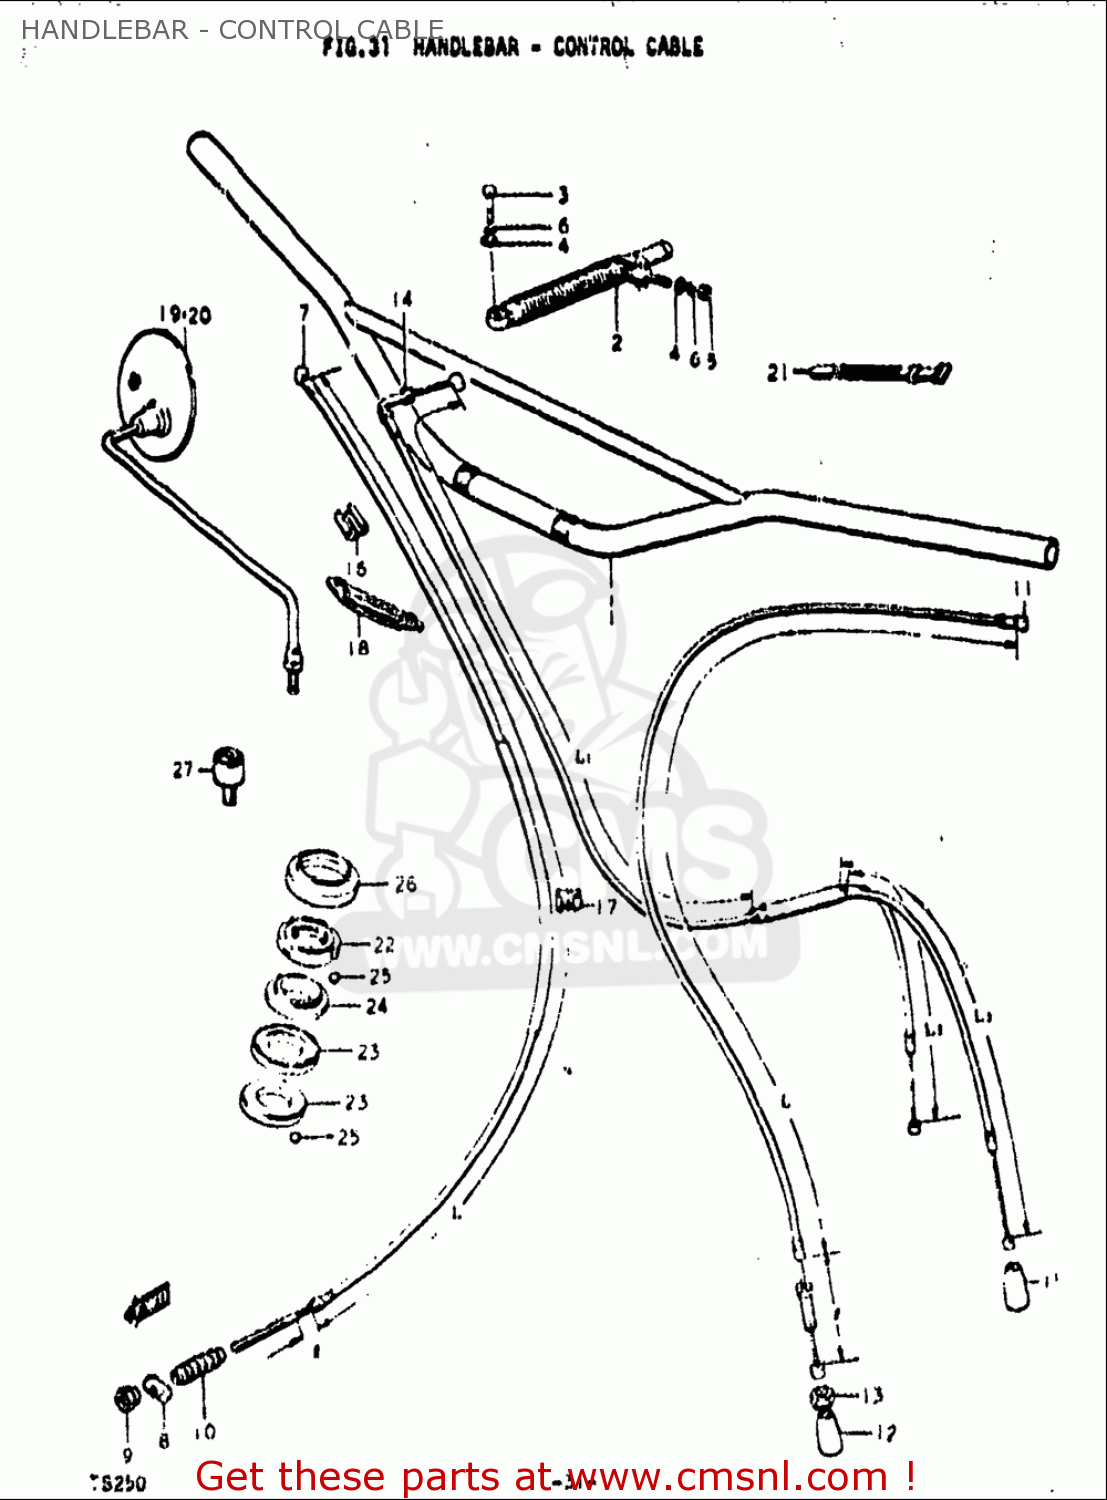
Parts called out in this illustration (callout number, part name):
3	BOLT
4	WASHER
5	NUT
6	WASHER,LOCK
7	CABLE,FR BRAKE
8	PIN(13X18)
9	NUT
10	SEAL,DUST
11	WIRE,CLUTCH
13	NUT
14	CABLE ASSY,THROTTLE
15	SEAL,DUST(7X18X30)
16	CLIP
17	CLIP
19	MIRROR ASSY,RR VIEW,R
20	MIRROR ASSY,RR VIEW,L
21	CLAMP(L:120)
22	NUT,STEERING STEM(25X44X10)
23	LACE,STEERING INNER LWR
24	LACE,STEERING OUTER UPR
25	BALL
26	DUST SEAL,STEERING UPR
